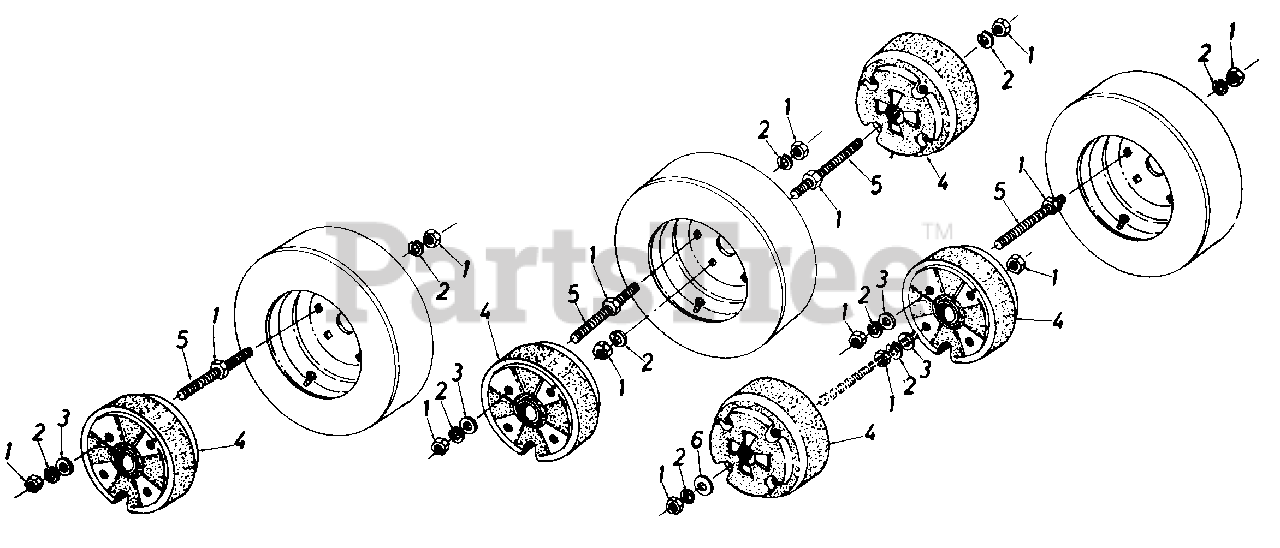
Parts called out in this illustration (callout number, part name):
1	Hex Nut 1/2-13Thd.
2	Lock Washer 1/2" I.D.
3	FlatWasher.53" I.D. x.93" O.D.
4	Wheel Weight
5	Rod Threaded 1/2-13 x 9.50 Lg.
6	Fl.-Wash. .50" I.D. x 2.00" O.D.
